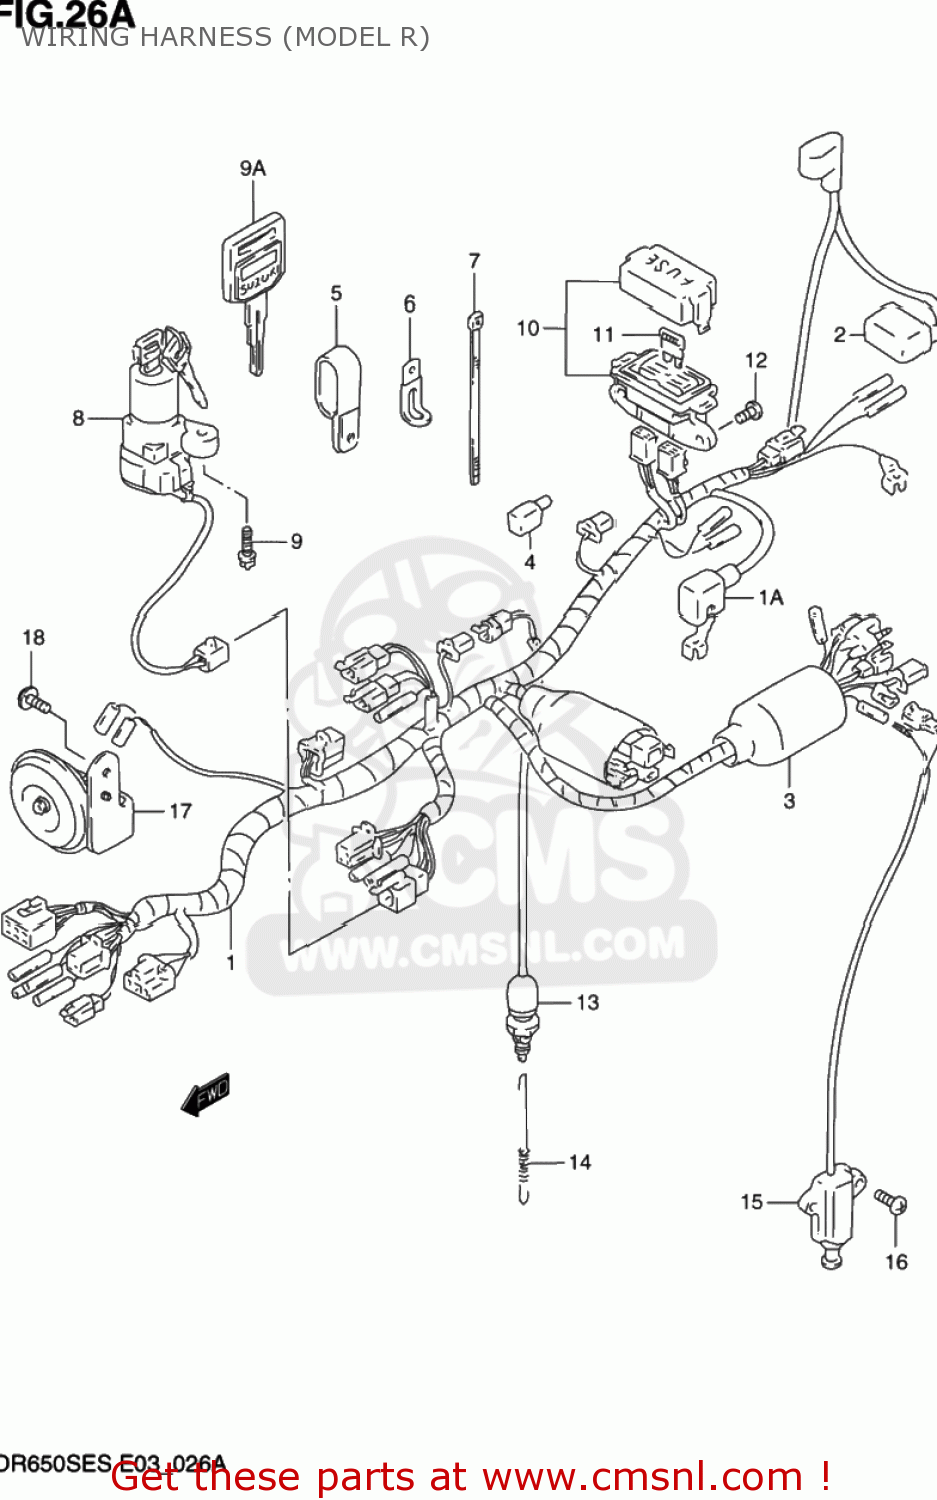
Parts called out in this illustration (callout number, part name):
1	HARNESS,WIRING
1A	CAP,BATTERY PLUS
2	CAP,STARTER RELAY
3	BOOT,WIRING HARNESS
4	COVER,DECOMPRESSION CONTROL UNIT
5	CLAMP
6	CLAMP
7	CLAMP L:165
8	LOCK ASSY,STEERING
9	SCREW(6X18)
9A	KEY,BLANK
10	BOX ASSEMBLY,FUSE
11	FUSE(10A)
12	SCREW 6X12
13	SWITCH ASSY,STOP LAMP
14	SPRING
15	SWITCH ASSY,SIDE STAND
16	SCREW, 6X20
17	HORN ASSY
18	BOLT
